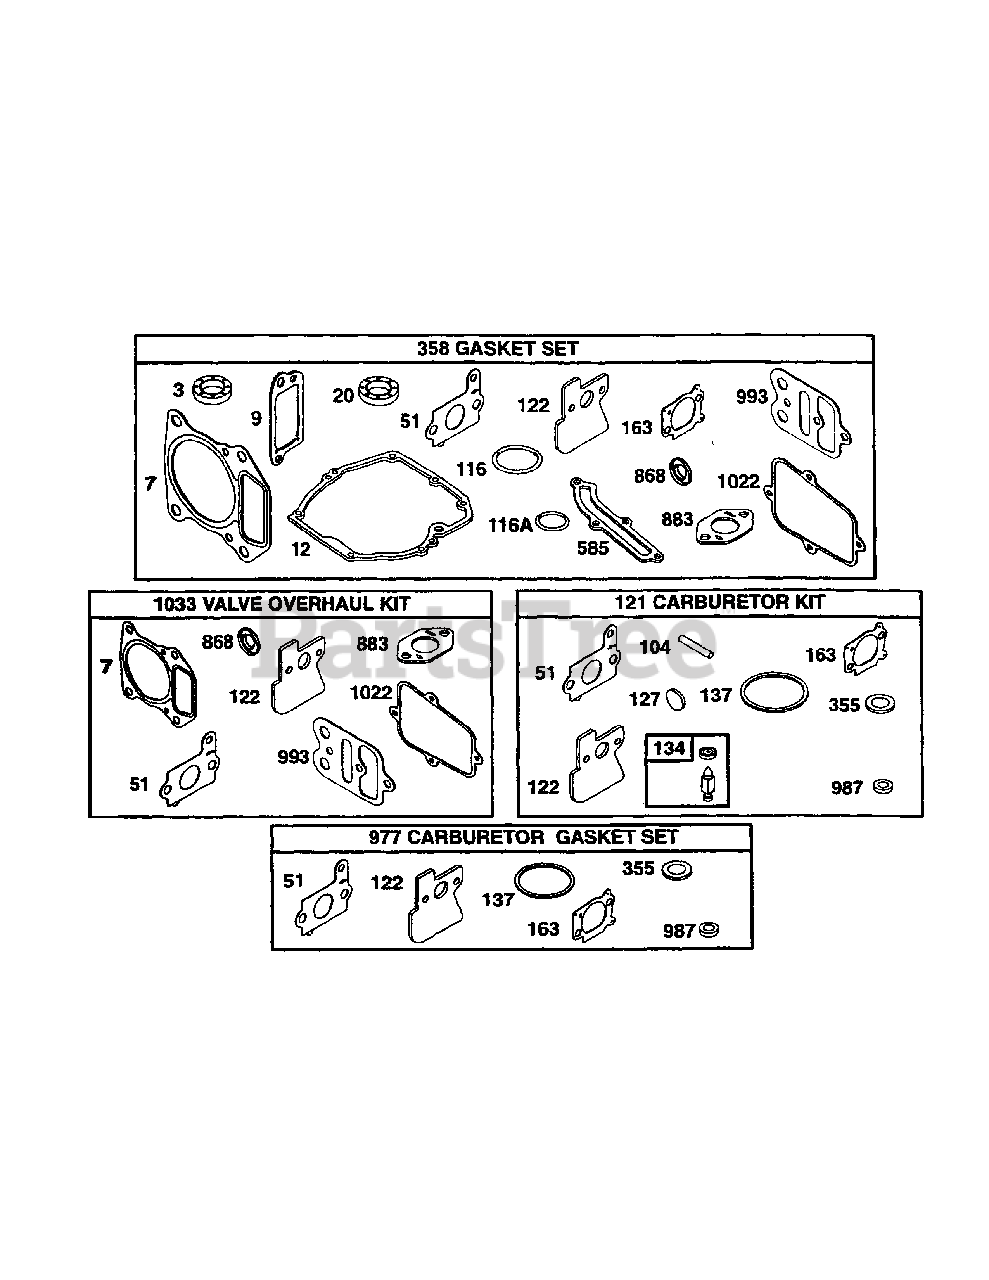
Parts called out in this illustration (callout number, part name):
3	Oil Seal
7	Cylinder Head Gasket
9	Breather Gasket
12	Crankcase Gasket
20	Oil Seal
51	Intake Gasket
104	Float Pin
116	O-Ring Seal
116A	O-Ring Seal
121	Carburetor Kit
122	Intake Gasket
127	Welch Plug
134	Needle Valve
137	Float Bowl Gasket
163	Air Cleaner Gasket
355	Seal Washer
358	Gasket Set
585	Breather Passage Gasket
868	Valve Seal
883	Exhaust Gasket
977	Gasket Set Carburetor
987	Throttle Shaft Seal
993	Plate Gasket
1022	Rocker Cover Gasket
1033	Valve Overhaul Kit
